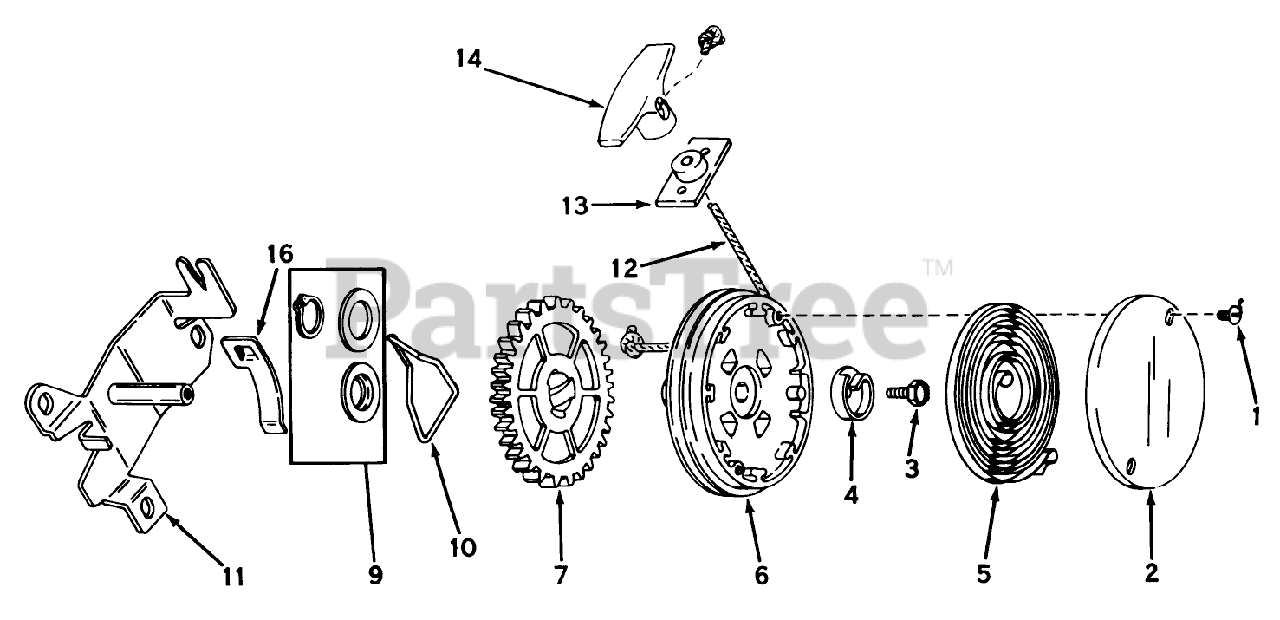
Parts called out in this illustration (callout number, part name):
1	Screw, Cover
2	Cover, Spring
3	Screw, Hex Washer Head
4	Hub Spring
5	Spring, Rewind
6	Pulley Assy. (Incl. No. 9)
7	Gear
9	Kit, Thrust Wash. & Snap Rg.
11	Bracket Assy. Mounting
12	Rope, Starter
13	Bracket Assy.
14	Handle-Starter
16	Clip Rope
